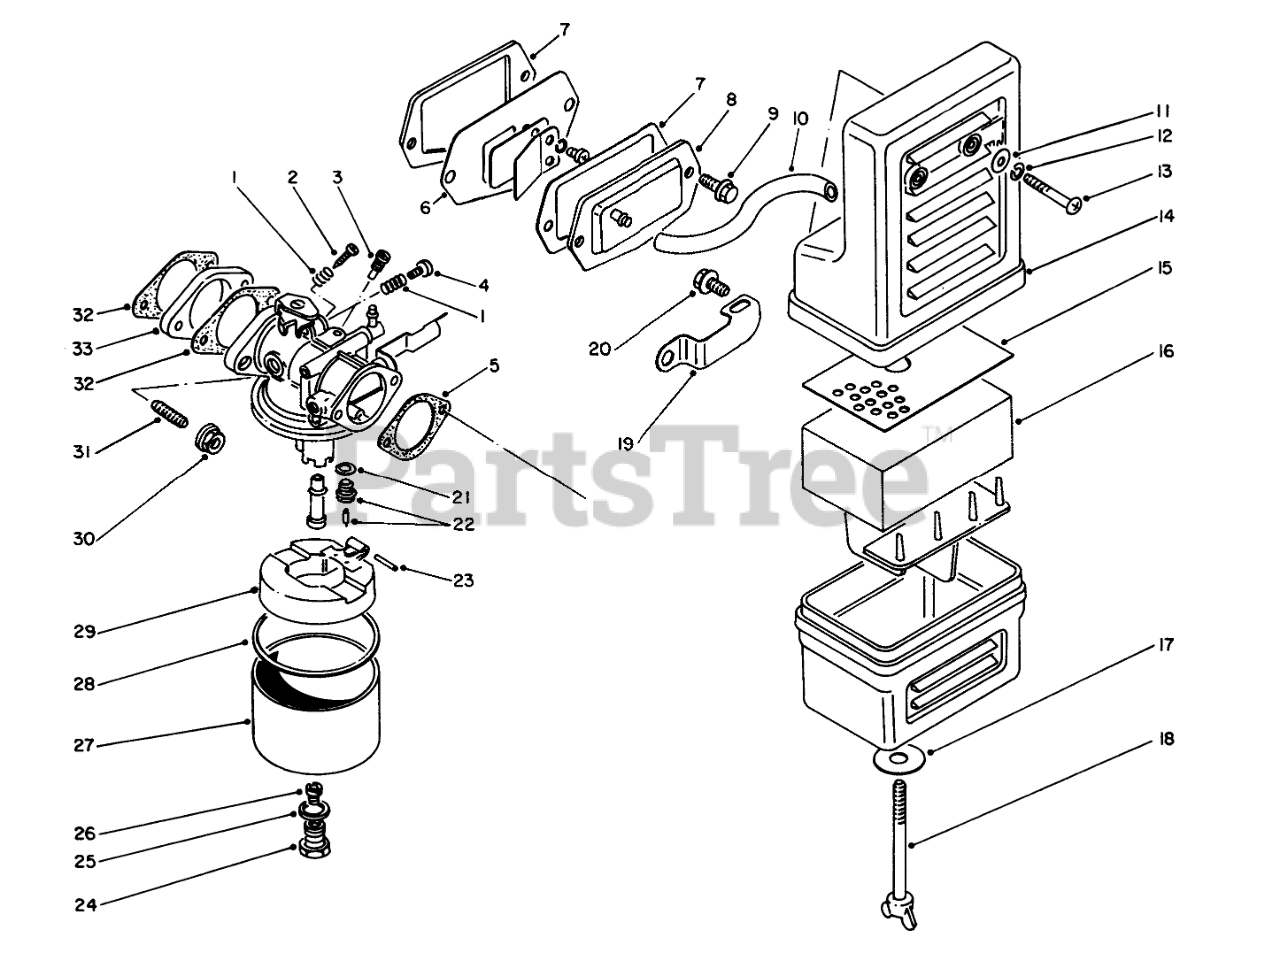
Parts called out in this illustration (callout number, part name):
1	Spring
2	ADJUSTER
3	Jet
4	SCREW
5	AIR CLEANER GASKET
6	Reed Valve Assembly
7	GASKET
11	WASHER
12	Washer
13	SCREW
14	Air Cleaner Assembly (Incl. Ref. #15-18)
15	Holder
16	FILTER
17	WASHER
18	Bolt-Wing
19	Bracket
21	GASKET
22	NEEDLE VALVE
25	GASKET
26	MAIN JET
27	Carburetor Assembly (Incl. Ref. #1-4, 21-26 8 28-29)
28	GASKET
29	FLOAT
31	Bolt-Stud
32	Gasket
33	INSULATOR
